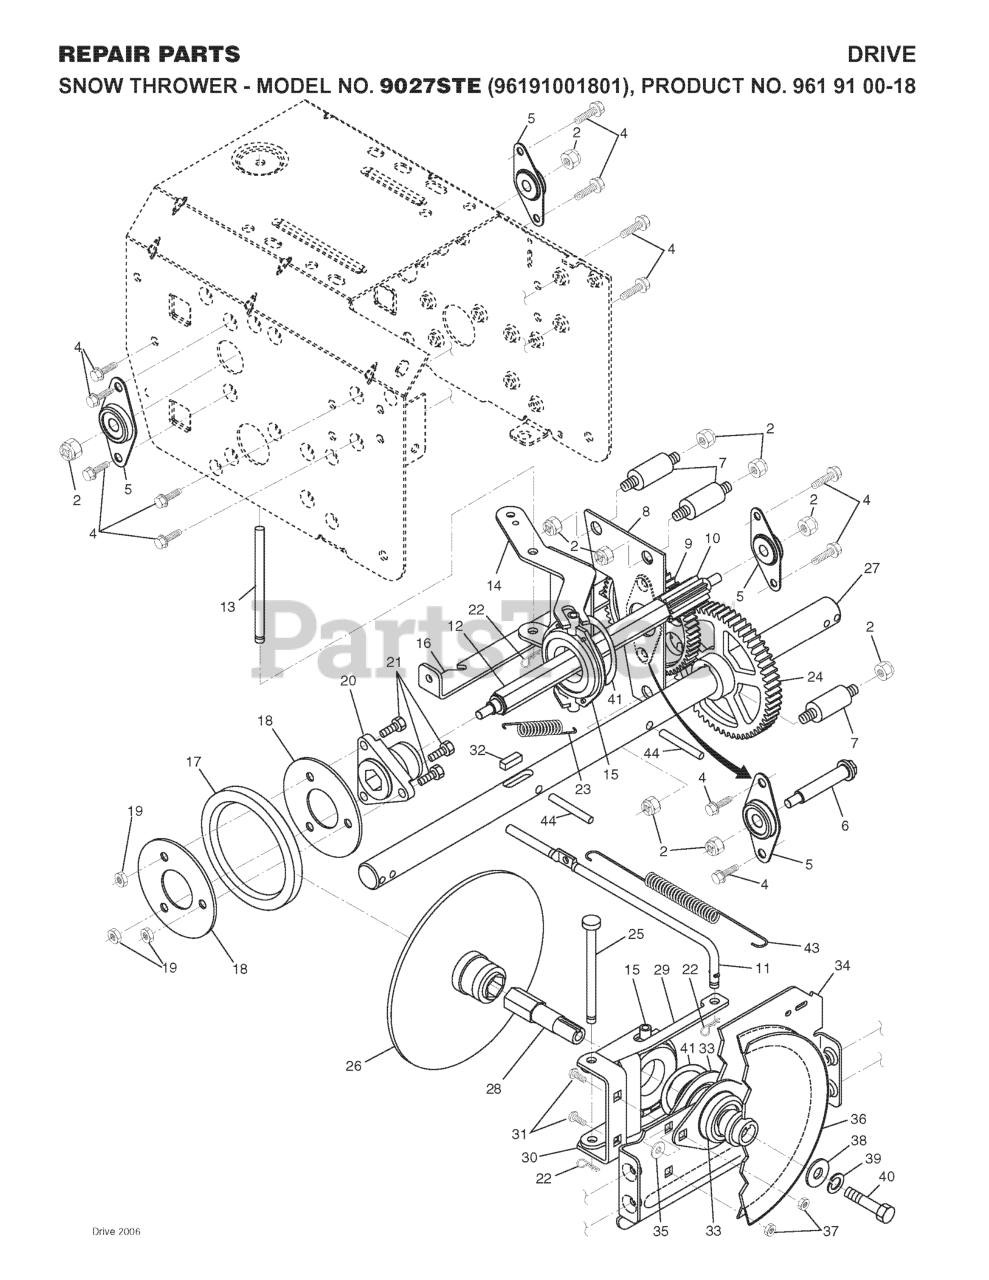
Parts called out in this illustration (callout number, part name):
2	NUT.LOCK.5/16-18
4	Screw 5/16-18 x 1/2 Hex, Self Tapping 5/16-18 x 1/2
5	BEARING, FLANGE
6	SHAFT, AUXILIARY
7	SPACER, PLATE
8	AUXILLARY PLATE
9	GEAR, INTERMEDIATE
10	GEAR, PINION
11	ROD.CLUTCH.YELLOW.ZINC
12	SHAFT.HEX.LONG
13	PIN, PIVOT
14	LEVER, SPEED CONTROL
15	TRUNNION BEARING ASSY
16	BRACKET, PIVOT, SHIFT
17	RING, RUBBER WHEEL
18	PLATE.RUBBER.WHEEL
19	NUT.CENTERLOCK.5/16-
20	HUB, RUBBER WHEEL
21	BOLT
22	RETAINER CLIP PM
23	SPRING, BIAS
24	GEAR, AXLE (58T)
25	PIN, PIVOT LEVER
26	DRIVE PLATE WELDMENT
27	SHAFT.AXLE.POWER.STEERING
28	SHAFT.HEX.SHORT
29	LEVER.SHIFTER.PLATE.BLACK
30	BRACKET, SHIFTER SUPPORT
31	BOLT
32	KEY, SQUARE 1/4 X .875
33	BEARING FLANGE
34	PLATE.DRIVE.MOUNTING.BLACK
35	SPACER, BEARING
36	PULLEY.TRACTION.7.75
37	NUT.FLANGE.5/16
38	WASHER, FLAT
39	WASHER.LOCK.HVY.HLCL.SPR.5/16
40	Screw, Hex Head 5/16-18 x 3/4
41	RETAINING RING (2 2)(3 2)
43	SPRING.RETURN
44	PIN.ROLL.3/16
